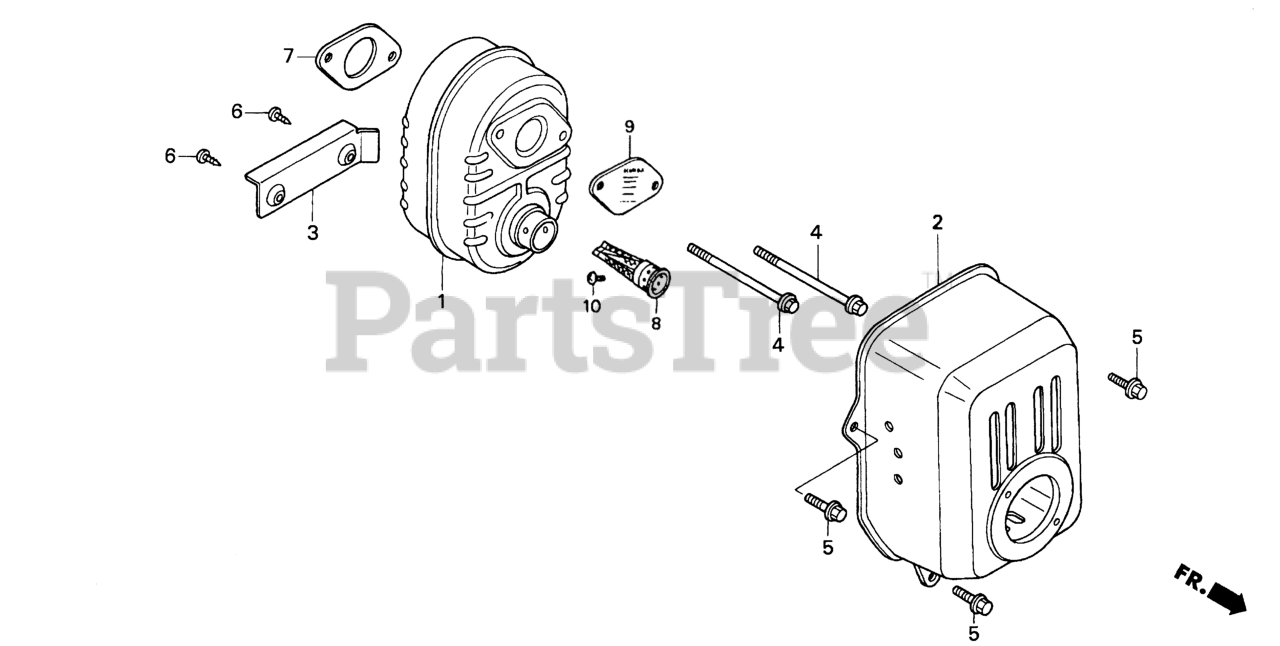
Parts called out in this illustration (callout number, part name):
2	PROTECTOR, MUFFLER (BLACK)
3	SHROUD, MUFFLER
4	BOLT, FLANGE (6X79) (CT200)
5	BOLT, FLANGE (6X12) (CT200)
6	SCREW, TAPPING (4X6) (TO INSTALL OPTIONAL SPARK ARRESTER)
7	GASKET, MUFFLER
